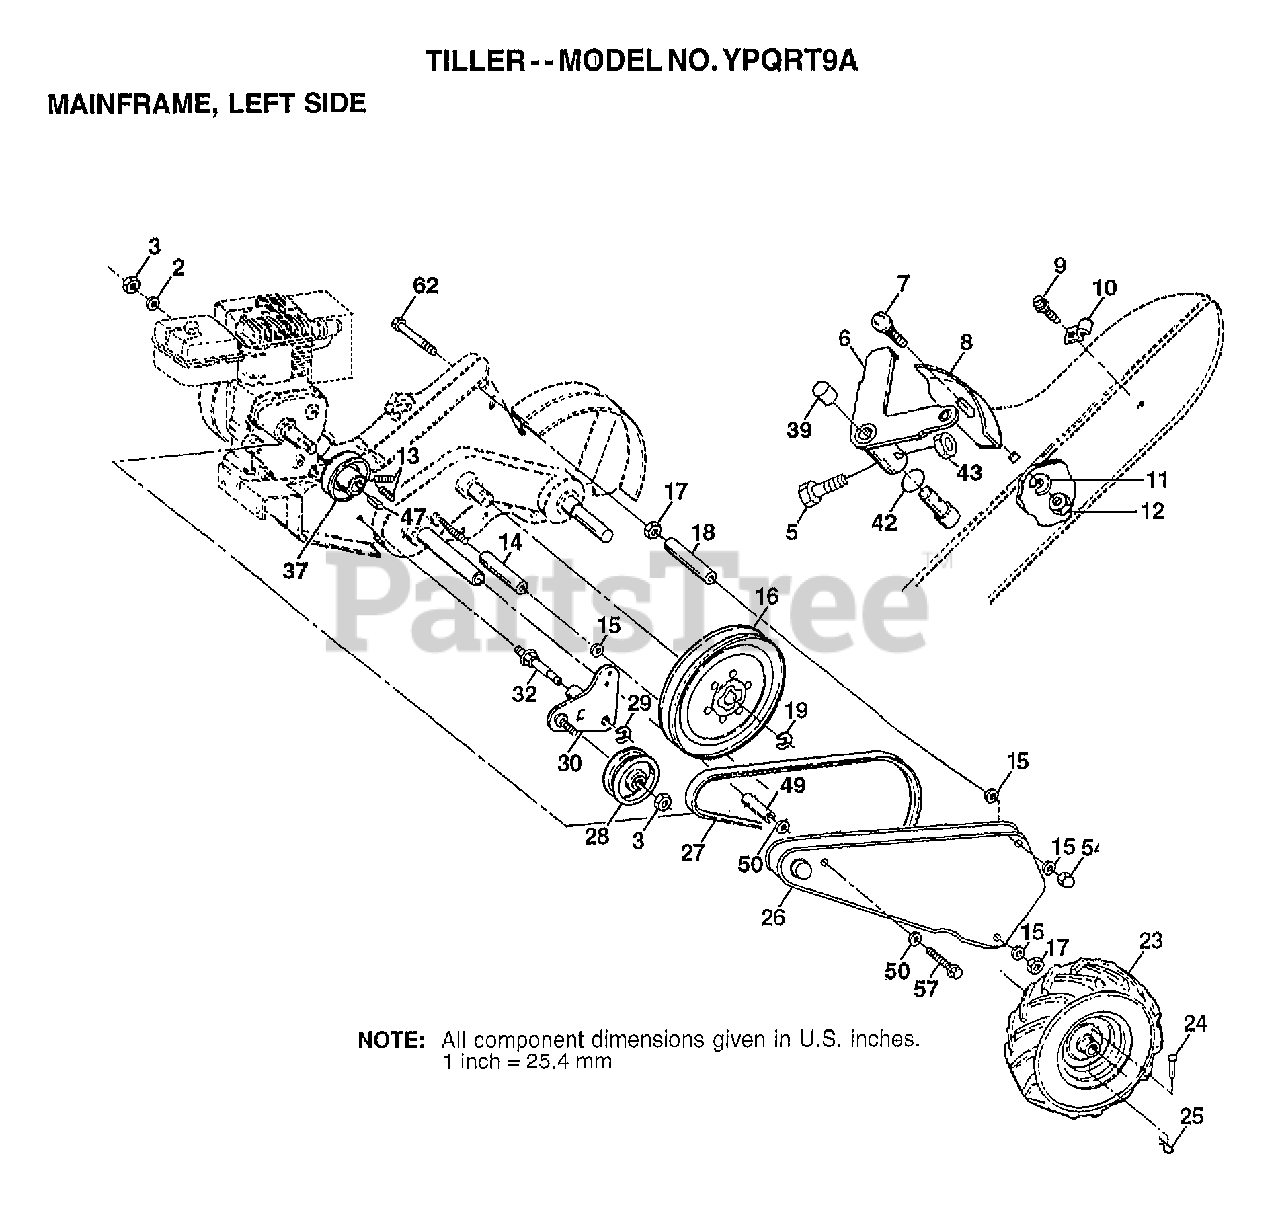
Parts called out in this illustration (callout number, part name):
2	LOCKWASHER
3	NUT.HEX.3/8-16UNC
5	"SCREW-LEVER,SHI"
6	LEVER ASM CRT
7	BOLT
8	PANEL TI
10	CONDIUT CLIP T
11	LOCKWASHER
13	SET SCREW
14	SPACER TI
15	WASHER
16	SHEAVE.TRANS.
17	NUT.HEX.5/16-18
18	SPACER TI
23	TIRE TI
23	RIM.16X4X8.WHT
24	RIVET.PAN HD.1.75
25	SPRING.RETAINER
27	BELT.DRIVE
28	PULLEY-IDLER TI
29	KLIP RING
30	BRACKET ASM IDLER
32	SHAFT.IDLER
37	SHEAVE CRT
39	CAP PLUNGER BLACK
42	O-RING TI
43	LOCKNUT
47	KEY TI
49	SPACER SPLIT
54	NUT TI
57	BOLT1/2-20UNF2.75
62	BOLT TI
